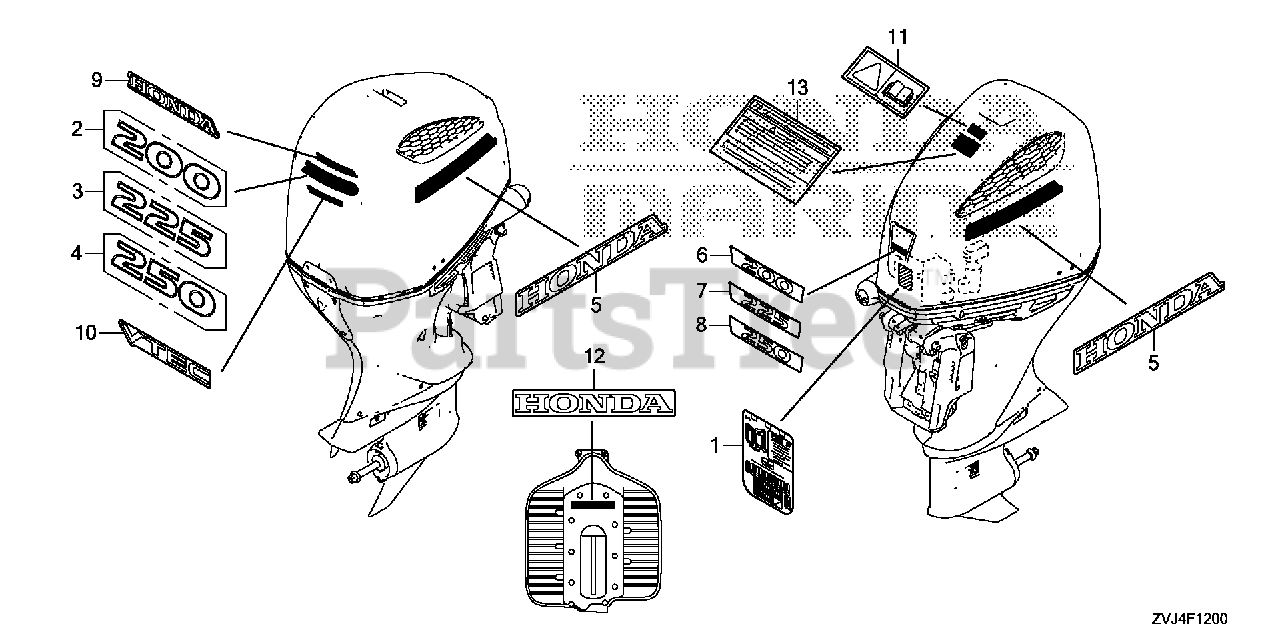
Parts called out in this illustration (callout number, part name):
1	LABEL, FUSE & OIL CAUTION
3	MARK, RR. (BF225)
5	MARK, SIDE STRIPE (BF250)
7	MARK, FR. EMBLEM (BF225)
9	MARK, HONDA
10	MARK (VTEC)
12	EMBLEM (13) (HONDA)
13	LABEL, WARNING OPERATOR (ENGLISH)
